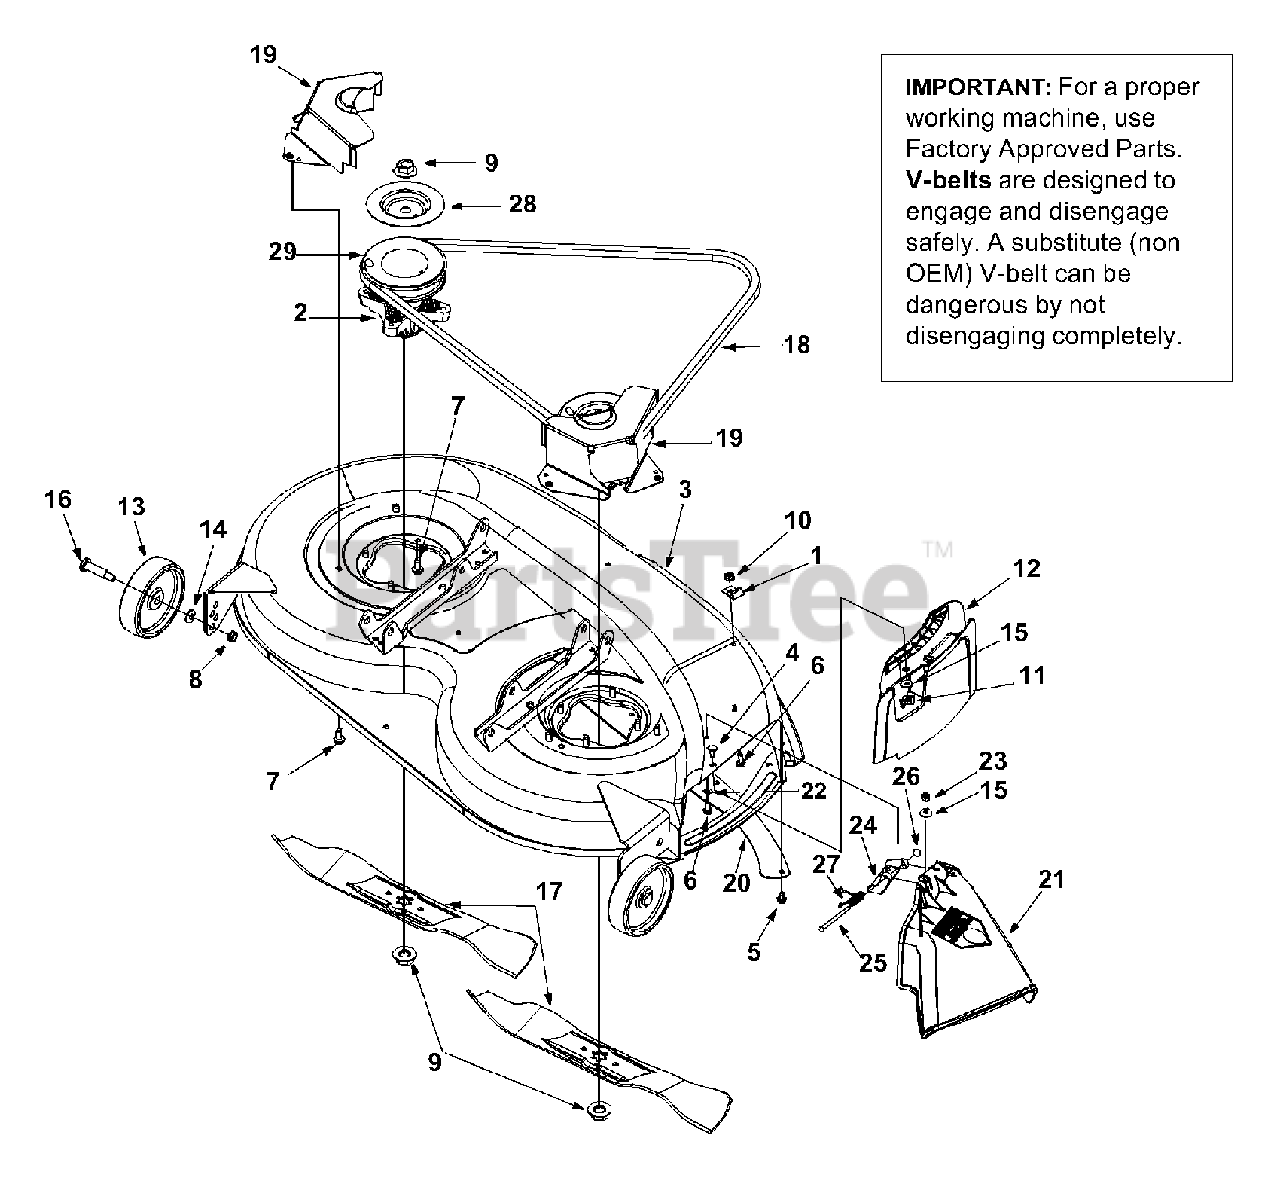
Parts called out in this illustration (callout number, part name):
1	Retainer Hook Brkt.
2	Blade Spdl Ass'y
5	Hex Wash. Hd. TT-Tap Scr. 1/4-20 Thd.
6	Hex Bolt 1/4-20 x .62" Lg.
7	Hex Wash. TT-Tap Scr. 5/16-18 x .75"
8	Hex Top L-Nut 3/8-16 Thd.
9	Hex Flange Nut 5/8-16 Thd.
10	Hex Flange Nut 1/4-20 Thd.
11	Wing Nut 1/4-20
12	Mulch Plug
13	Deck Wheel
14	Bell-Wash. .40" I.D. x .88" O.D.
15	Bell-Wash. 1/4" I.D.
16	Shoulder Screw
17	3 in 1 blade
18	V Belt
21	Chute Ass'y
22	Push Nut
23	Hex Nut 1/4-20 Gr. 5
24	Hinge Mounting Brkt.
25	Hinge Pin
26	Speed Nut Cap
27	Torsion Spring
28	Brake Disc
29	5" Dia. Pulley
